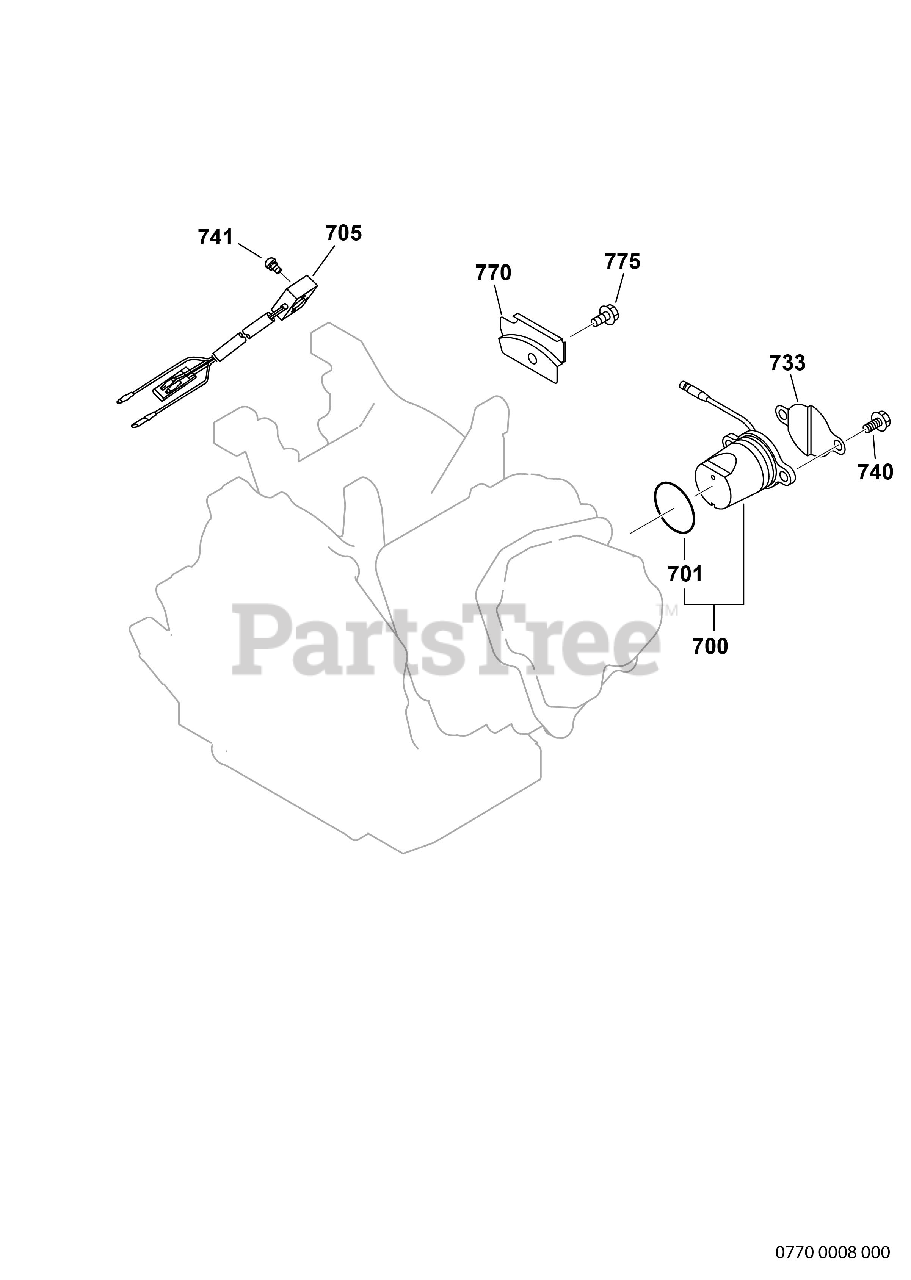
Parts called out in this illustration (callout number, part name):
733	SHIELD PLATE(O/S)
740	BOLT AND WASHER AY
741	FLANGE BOLT
775	TAPPING BOLT
